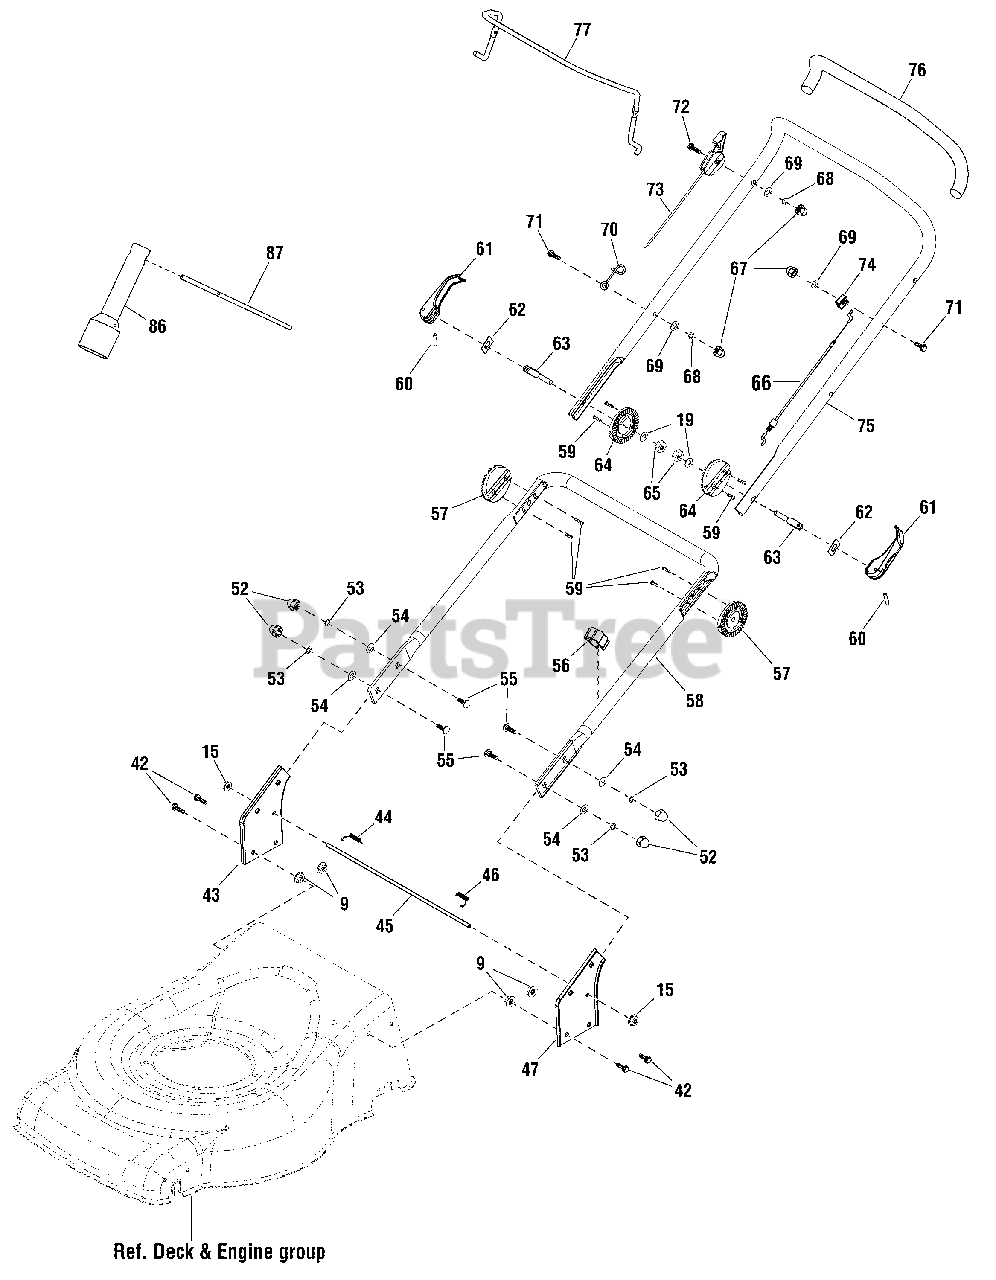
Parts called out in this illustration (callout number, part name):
9	* NUT, Hex Lock
15	* NUT, Hex Lock
19	* WASHER, Flat
42	* BOLT, Hex
43	SUPPORT, Handle, RH
44	SPRING, RH
46	SPRING, LH
47	SUPPORT, Handle, LH
53	WASHER, Spring
54	* WASHER, Flat
55	BOLT, Cup Head Square Neck
56	* CLAMP, Cable
57	GEAR, Lower Adjustment
58	HANDLE, Lower
61	LEVER, Locking
63	BOLT, Lever
64	GEAR, Upper Adjustment
65	* BOLT, Hex
68	WASHER, Spring
69	* WASHER, Flat
70	CABLE HOOK
71	* BOLT, Hex
72	* BOLT, Hex
73	THROTTLE & CABLE ASSEMBLY
74	CLAMP, Cable
75	HANDLE, Upper
87	HANDLE, Wrench
